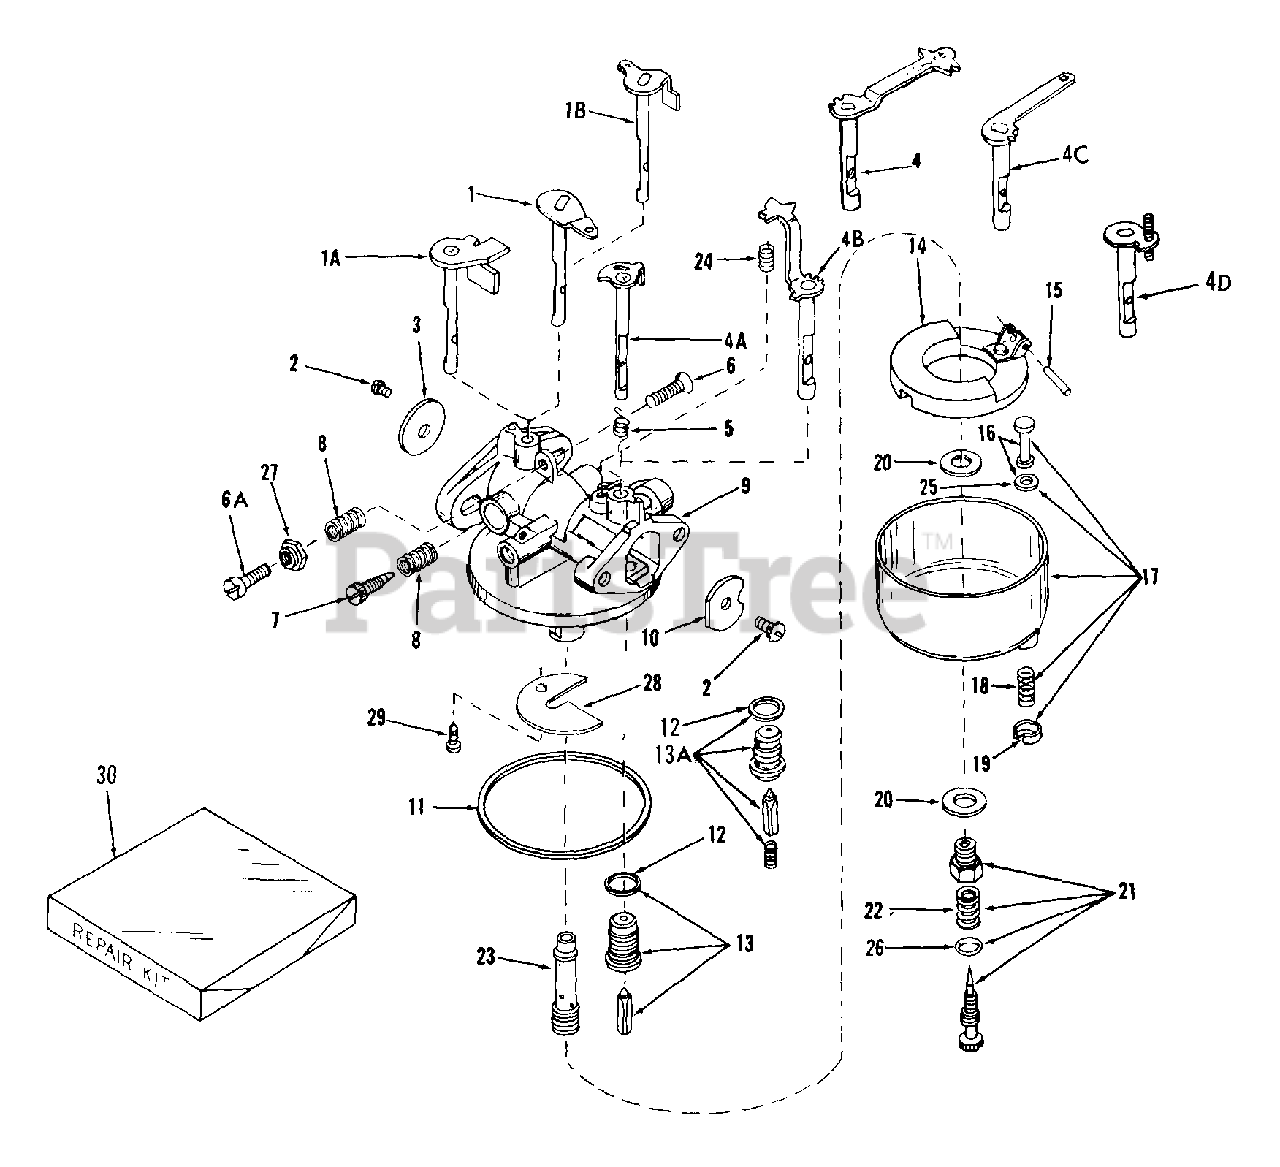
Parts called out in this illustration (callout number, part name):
1	"Shaft & Lever Assy., Throttle
2	Screw, Sems, 6-32 x 3/16
3	Shutter, Throttle
4	Shaft & Lever Assy., Choke
6	Screw, Throttle adjusting
8	Spring, Adj. needle
9	Body Assy., Carburetor
10	Shutter, Choke
11	Gasket, Bowl-to-body
12	Gasket, Seat
13	Valve, Seat & Gasket Assy. (Incl. No. 12)
15	Shaft, Float
16	Stem Assy., Bowl drain
17	Bowl Assy.
18	Spring, Bowl drain
19	Retainer, Bowl drain stem .
20	Gasket, Bowl-to-body
21	Neede Assy., Power adjusting (Inc.22, 26)
22	Spring, Power needle
23	Nozzle, Main
24	Spring, Choke stop
25	Gasket, Drain stem
26	"O" Ring
27	Nut, Flexloc
30	Repair Kit
